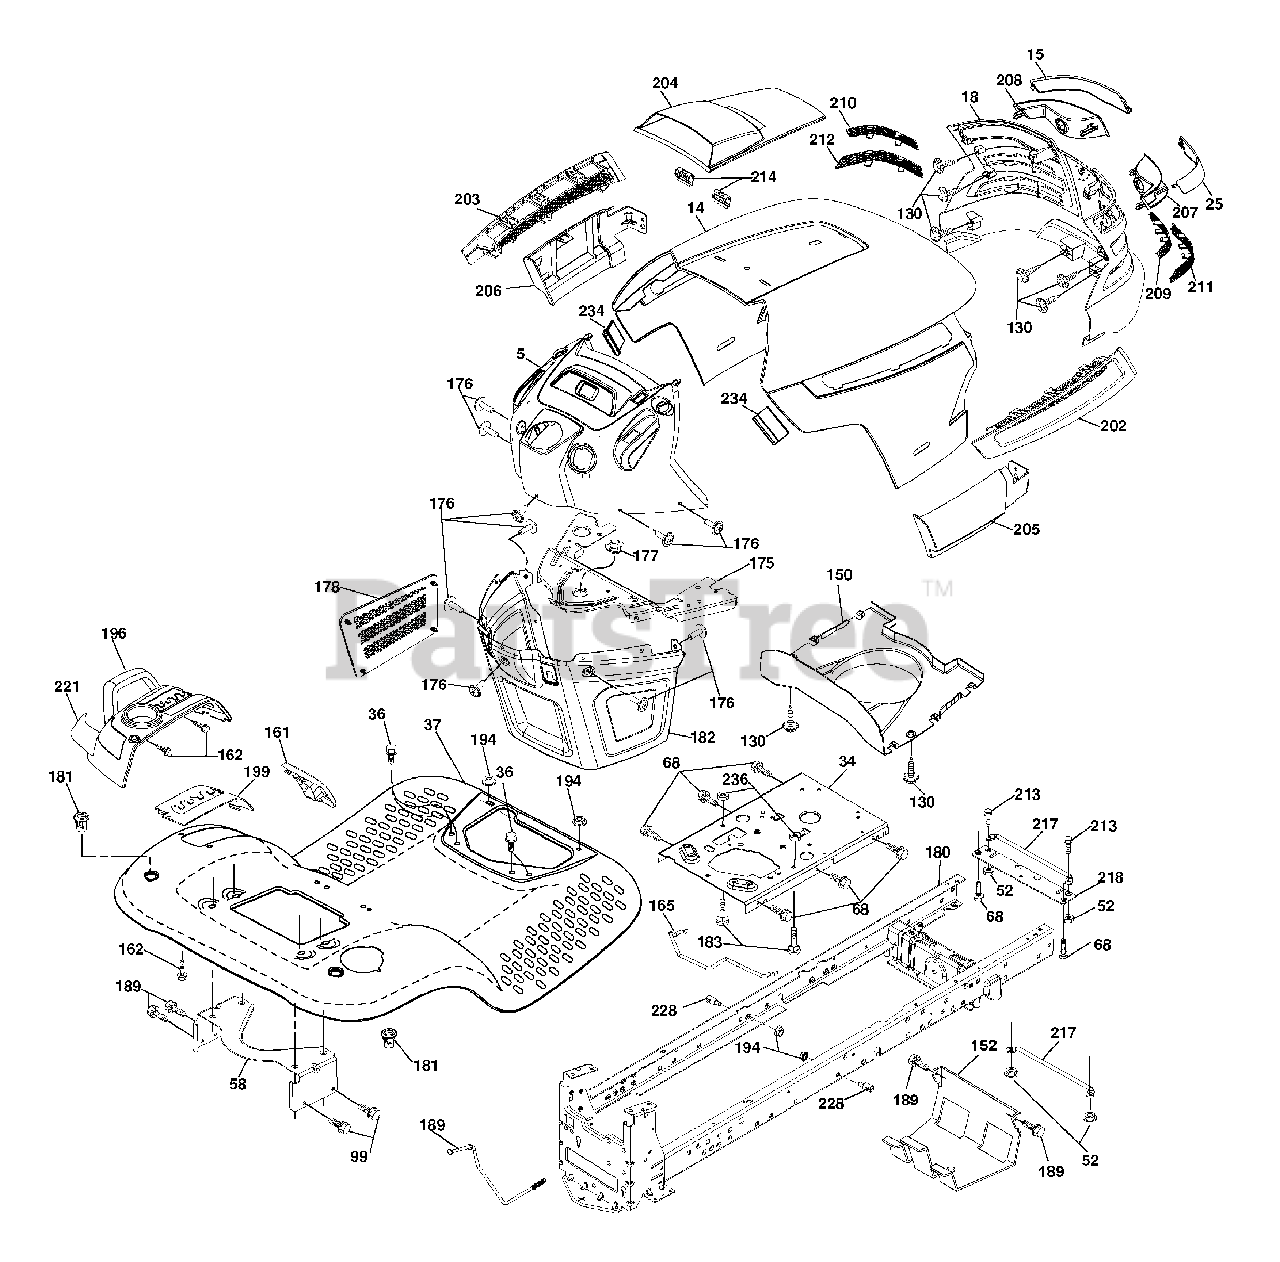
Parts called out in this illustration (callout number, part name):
14	Hood
18	Grille Asm.
34	Plate Engine
36	Screw 5/16-18 x 3/4
37	Fender
52	Nut Lock 5/16-18
58	Bracket Support Fender
68	Screw 5/16-18 x 1/2
99	Rod Asm Bypass
130	Screw 10 x 3/4 Single Lead-Hex
152	Shield Browning
161	Window Fuel
165	Support Tank Rear
175	Crossmember
176	Screw 10-24 x 5/8
177	Bushing Steering
178	Cargo Net Asm.
180	Chassis
181	Bushing Mtg. Fender Crgo
182	Dash Lower
183	Bolt Fin Hex 5/16-18 unc x 1-1/4
189	Screw 5/16-18 x 3/4
194	Nut Lock Hex Flange 5/16-18
196	Console Asm. Deck Lift
199	Plate Deck Lift
202	Vent Side Hood RH
203	Vent Side Hood LH
204	Vent Top Hood
205	Skirt Hood Side RH
206	Skirt Hood Side LH
209	Insert Hex Top RH
210	Insert Hex Top Lh
211	Insert Hex Bottom RH
212	Insert Hex Bottom LH
213	Bolt 5/16-18 UNC x 3/4
214	Clip Retainer Tinner
217	Rod Pivot
218	X-Piece Hood Stop
221	Reflector LH
228	Stud Fastner
234	Bumper Hood
235	Spacer Fender
236	Nut Lock 5/16-18 UNC
